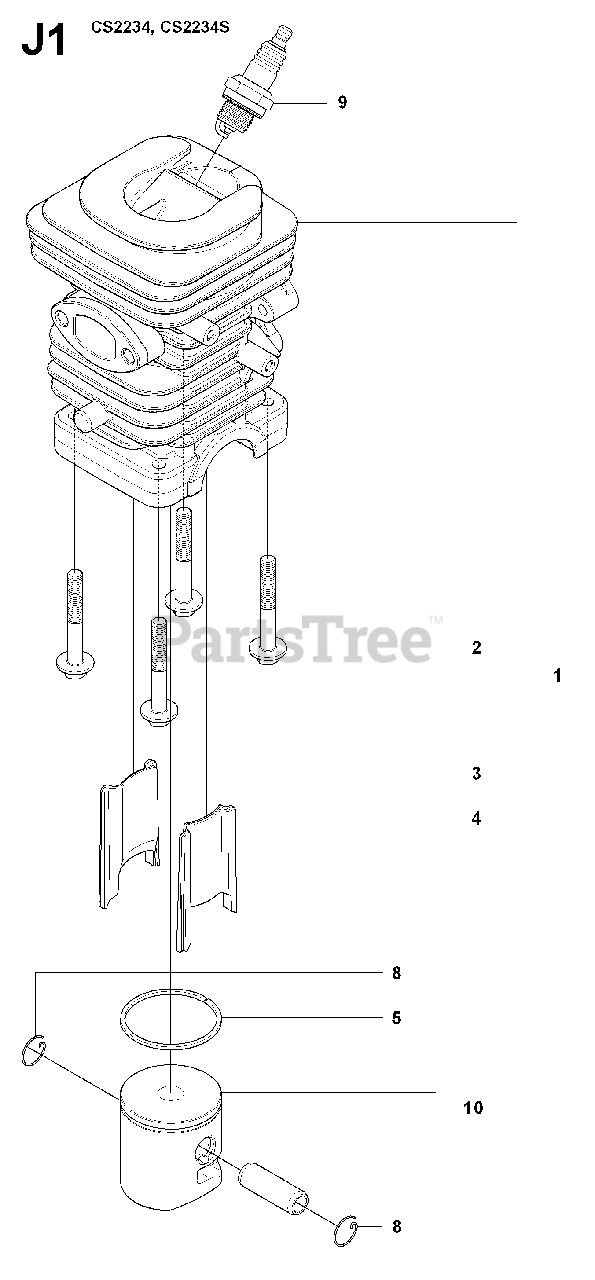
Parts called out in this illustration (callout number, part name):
1	KIT, CYLINDER & PISTON
2	BOLT
3	TRANSFER INSERT LEFT
4	TRANSFER INSERT RIGHT
5	PISTON RING
8	C-CLIP,PSTN PIN 36/41
9	SPARK PLUG RCJ7Y
10	PISTON KIT
